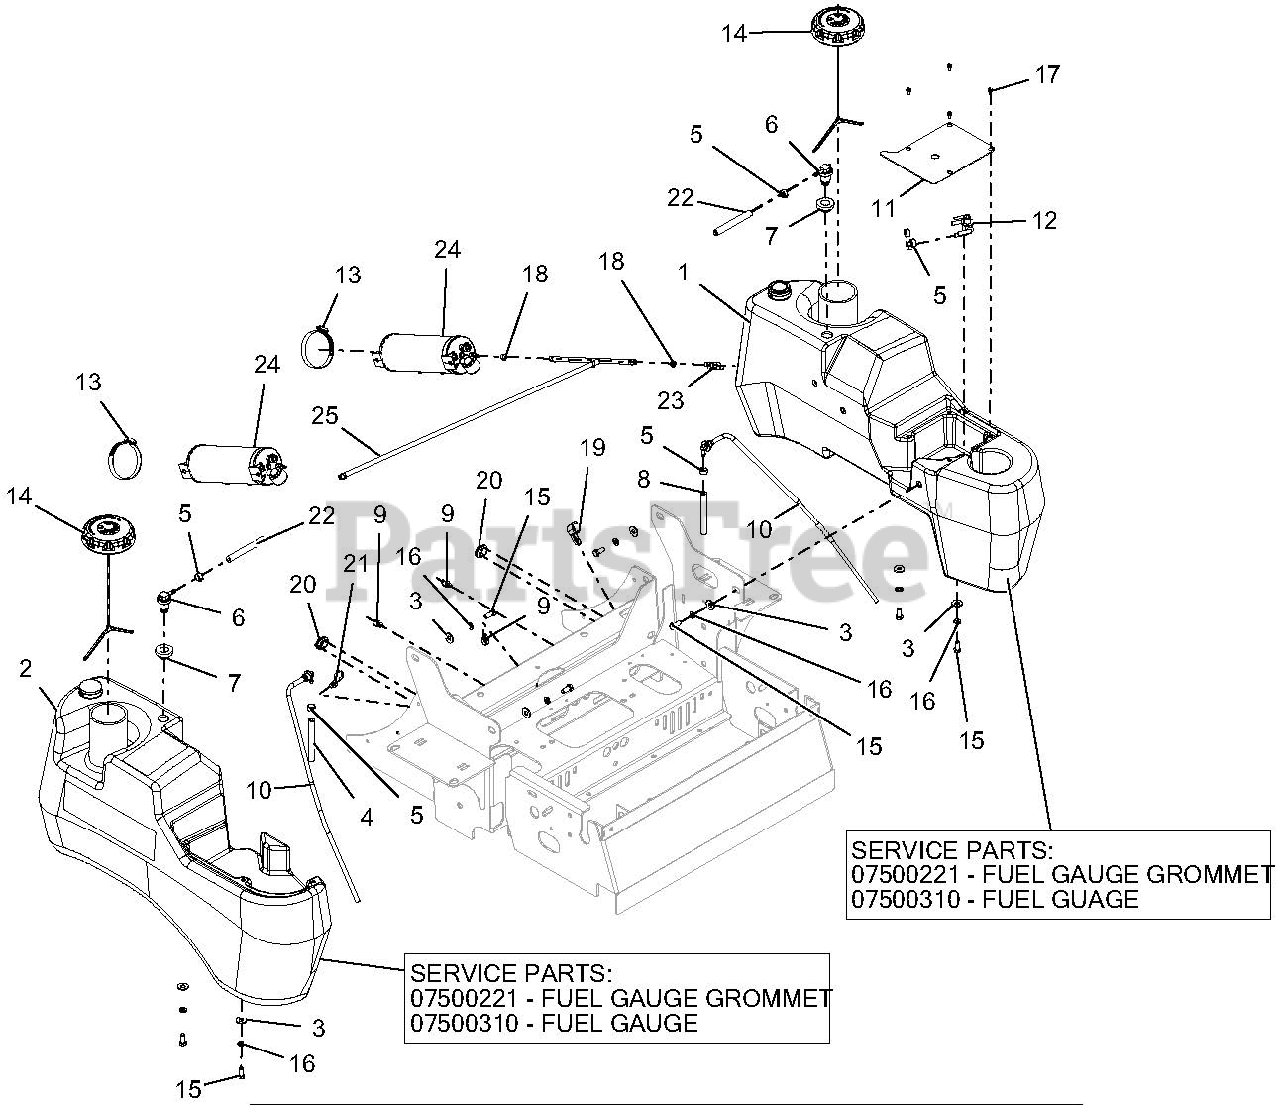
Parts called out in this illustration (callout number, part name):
1	ASSY-LH LARGE FUEL TANK W/MECH GAUGE-GAS
1	FUEL GAUGE GROMMET
1	FUEL GAUGE
2	ASSY-RH LARGE FUEL TANK W/MECH GAUGE-GAS
2	FUEL GAUGE GROMMET
2	FUEL GUAGE
3	WSHR-FL-STL.38X.875X.083 YWZC
4	.25 LOW-PERM GAS HOSE 54.00" LG - RH TANK TO VALVE
5	CLAMP, FUEL LINE
6	VALVE, COMBINATION
7	GROMMET, REMOTE VENT NITRILE
8	.25 LOW-PERM GAS HOSE 19.00" LG - LH TANK TO VALVE
9	CLIP, ROUTING (.50 ID)
10	ASM, LARGE TANK FUEL PICKUP
11	PLATE, FUEL VALVE MOUNTING-RED
12	VALVE, FUEL
13	CLAMP, HOSE 2.3/3.2
14	CAP, NON NONVENT AUTOLOCK
15	BLT-HEX .31-18X.75 GR5 YWZC
16	WSHR-LK .31X.078 REG YWZC
17	SCR-MCH 10-24X.38 HWHSTAINLESS
18	CLAMP - HOSE, SPRING .188
19	CLAMP, CUSHIONED STEEL .75
20	GROMMET, RUBBER
21	CABLE TIE W/ TREE (.25 HOLE)
22	.25 LOW-PERM GAS HOSE 14.00" LG - Tank vent to CARB canister
23	CLIP, T, .38-.50
24	CANISTER, CARBON 9.3 GAL
25	ASM, FUEL PICK-UP - LARGE TANK
